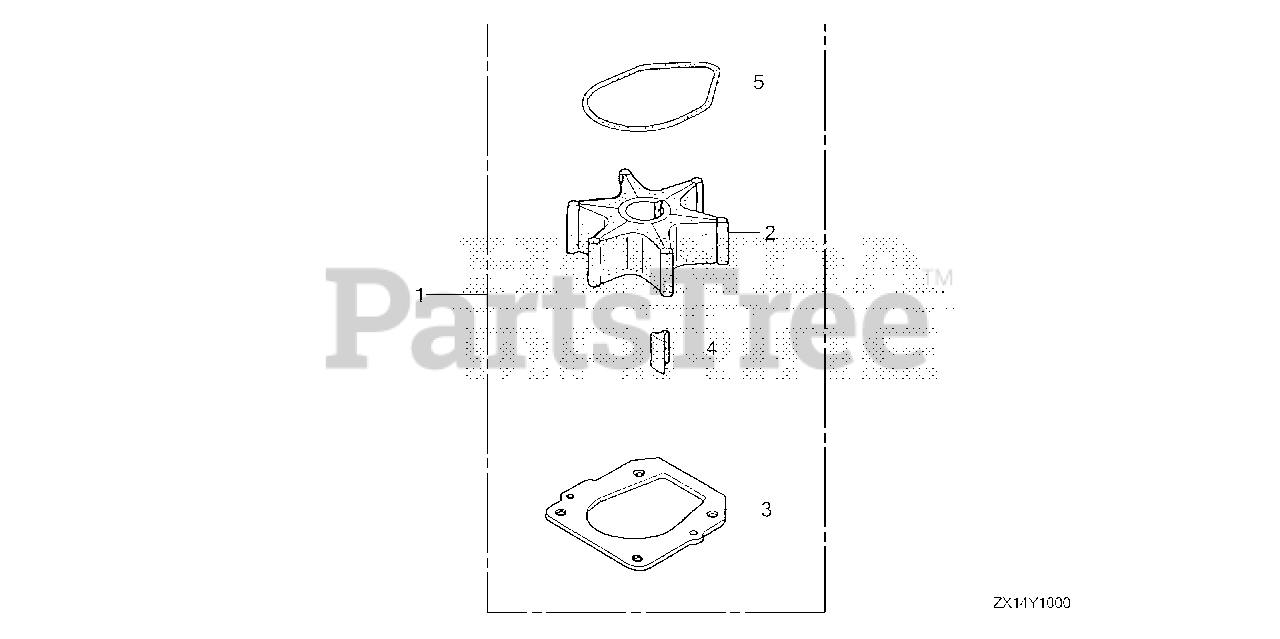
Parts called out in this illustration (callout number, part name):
1	PUMP KIT, IMPELLER
2	IMPELLER, PUMP
3	GASKET B, IMPELLER
4	KEY, WOODRUFF
5	O-RING, WATER PUMP
